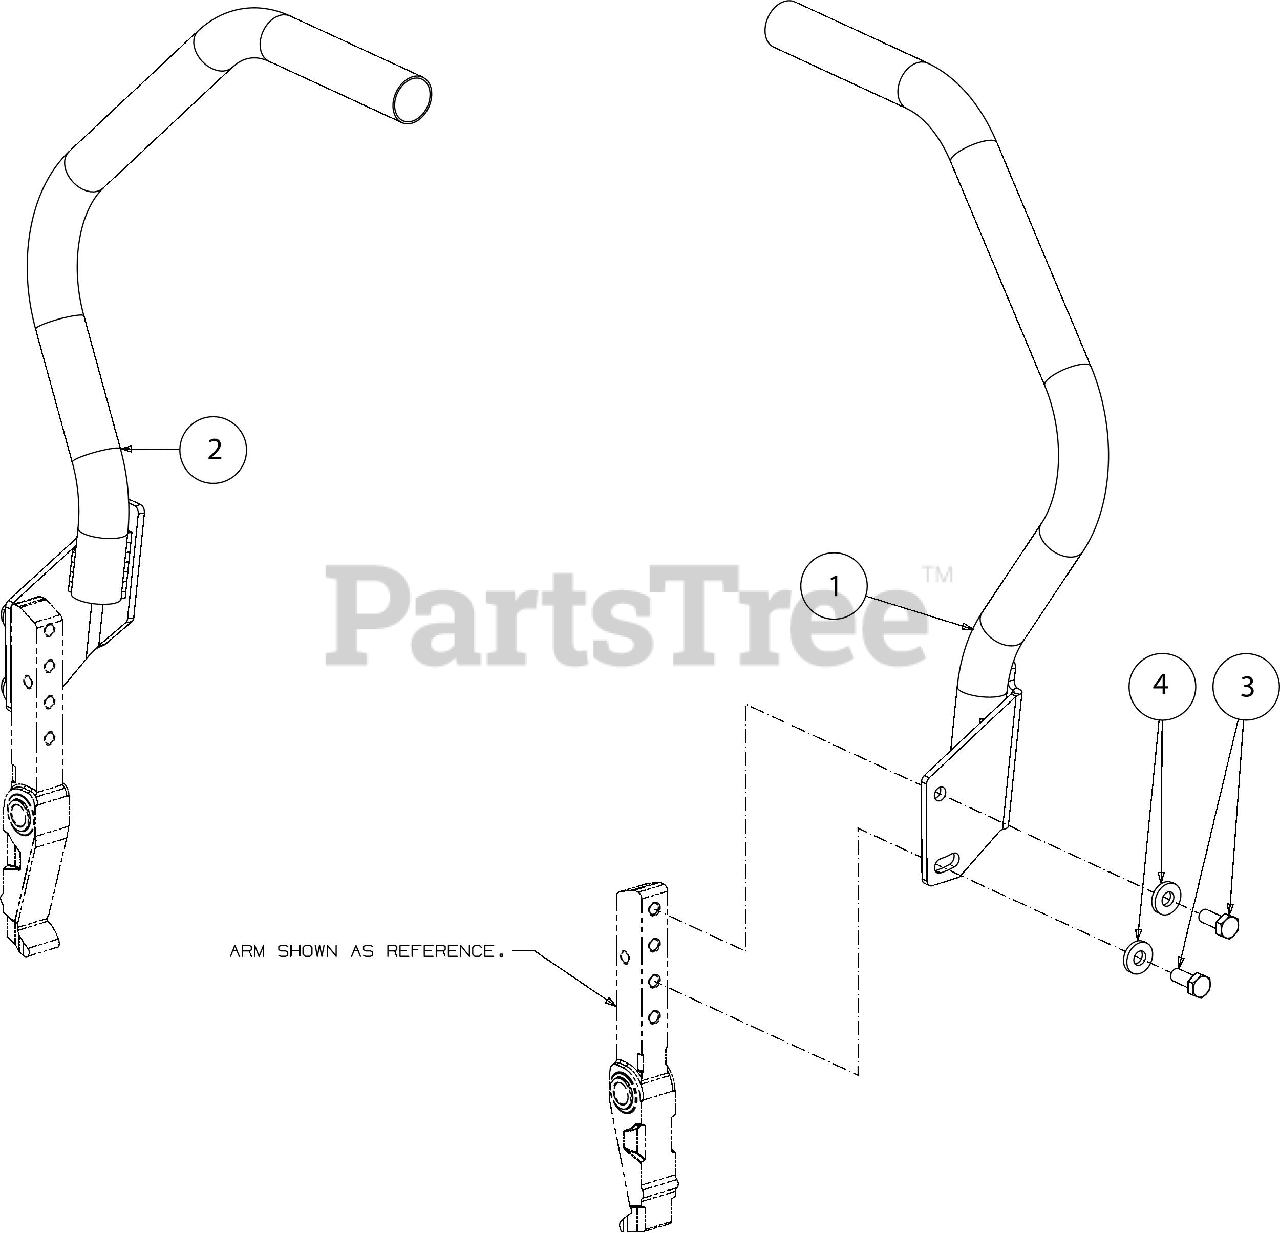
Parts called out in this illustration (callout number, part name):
1	LAPBAR HANDLE (RH)
2	LAPBAR HANDLE (LH)
3	SCREW 5/16-18 X .750
4	FLAT WASHER
